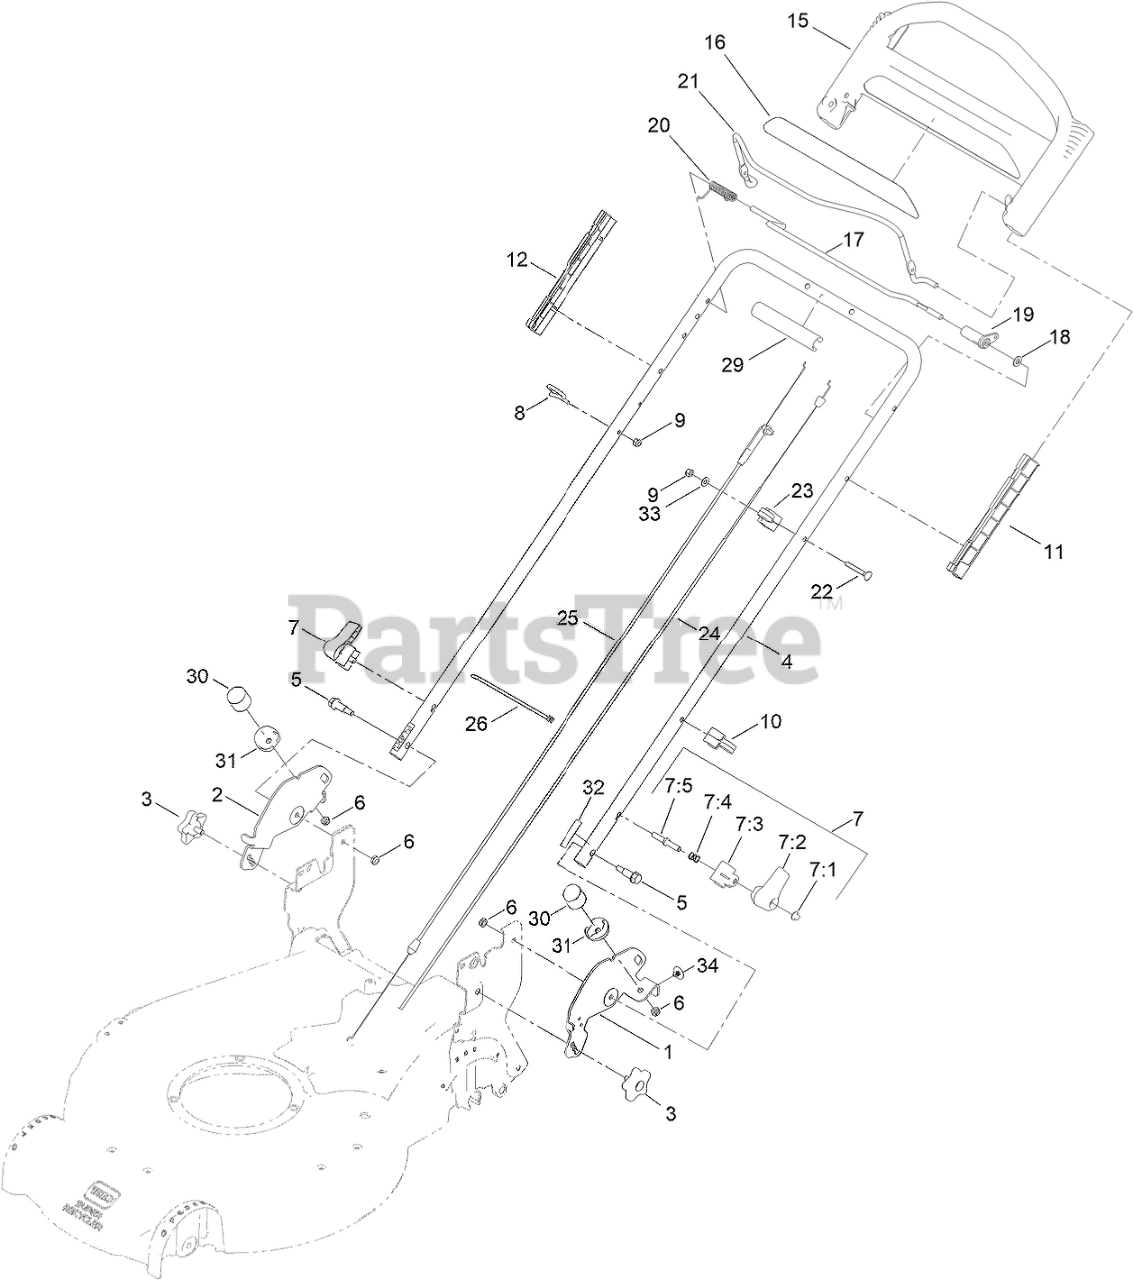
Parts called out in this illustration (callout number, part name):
1	BRACKET-FLOAT, LH
2	BRACKET-FLOAT, RH
3	KNOB-HANDLE
4	HANDLE-UPPER
5	BOLT-SHOULDER
6	NUT-LOCK, NI
7	QUICK RELEASE ASM
7:1	NUT-PUSH
7:2	LEVER-RELEASE
7:3	ANCHOR-SPRING
7:4	SPRING-COMPRESSION
7:5	ROD-RELEASE
8	GUIDE-ROPE
9	NUT-LOCK, NI
10	GUIDE-CABLE
11	GUIDE-LH
12	GUIDE-RH
15	HANDLE-CONTROL
17	BAR-CONTROL, TRACTION
18	WASHER-PLAIN
19	LEVER-TRACTION
20	SPRING-TORSION
21	BAIL-BRAKE
22	SCREW
23	ANCHOR-CABLE
24	CABLE-TRACTION
25	CABLE-BRAKE
26	TIE-CABLE
29	HANDLE-COVER
30	BUMPER-RUBBER
31	COVER-BUMPER
32	DECAL-FLEX
33	WASHER-FLAT
34	CLIP-TREE
